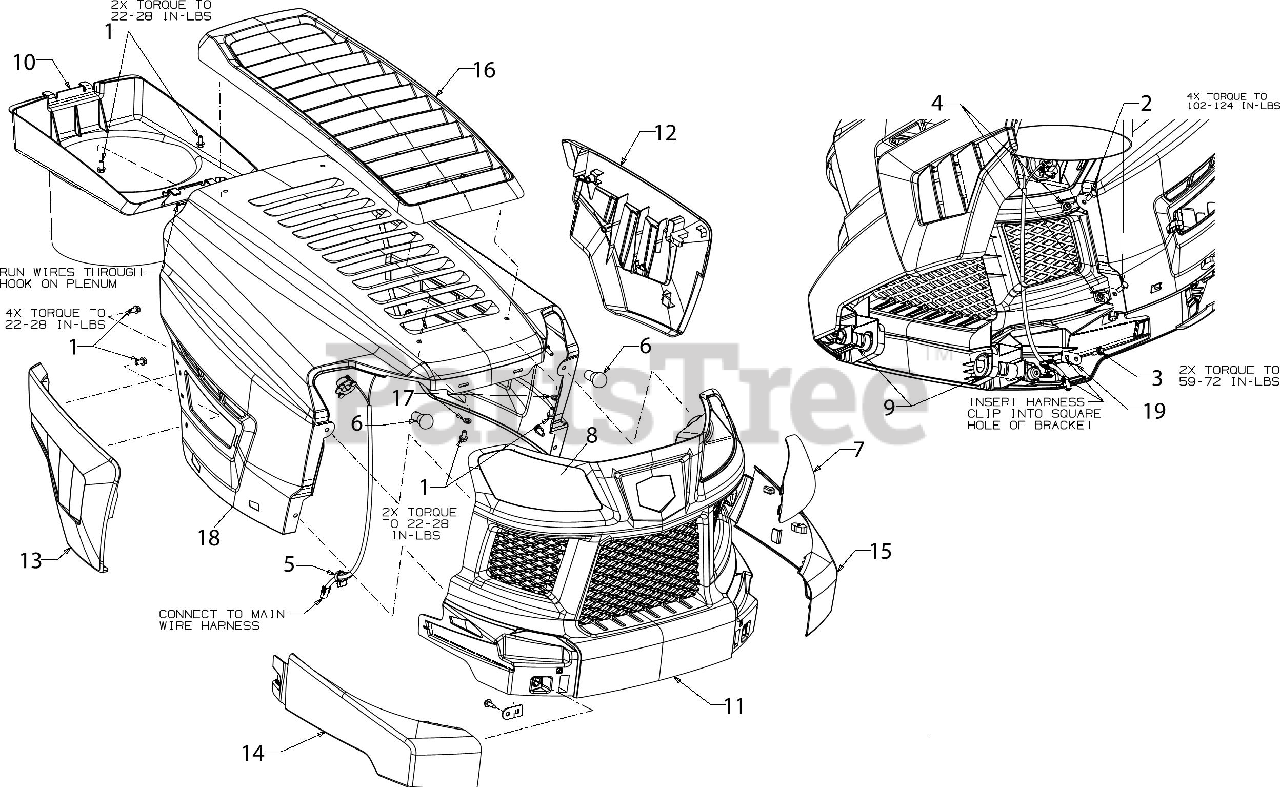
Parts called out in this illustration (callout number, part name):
1	HEX SCREW 1/4-15 x .50
2	SCREW 1/4-20 x .62 SPEC GR5
3	SCREW 1/4-10 x .750
4	SQUARE NUT 1/4-20
5	HEADLIGHT HARNESS
6	MINIATUURE BULB 12V
7	GRILLE LENS (LH)
8	GRILLE LENS (RH)
9	HOOD PIVOT PIN
10	HOOD PLENUM
11	GRILLE (CRAFTSMAN)
12	HOOD SIDE COVER (LH)
13	HOOD SIDE COVER (RH)
14	GRILLE PANEL- (RH)
15	GRILLE PANEL- (LH)
16	HOOD SCOOP
17	FLAT WASHER .281 x .50 x .063
19	HARNESS CLIP BRACKET
